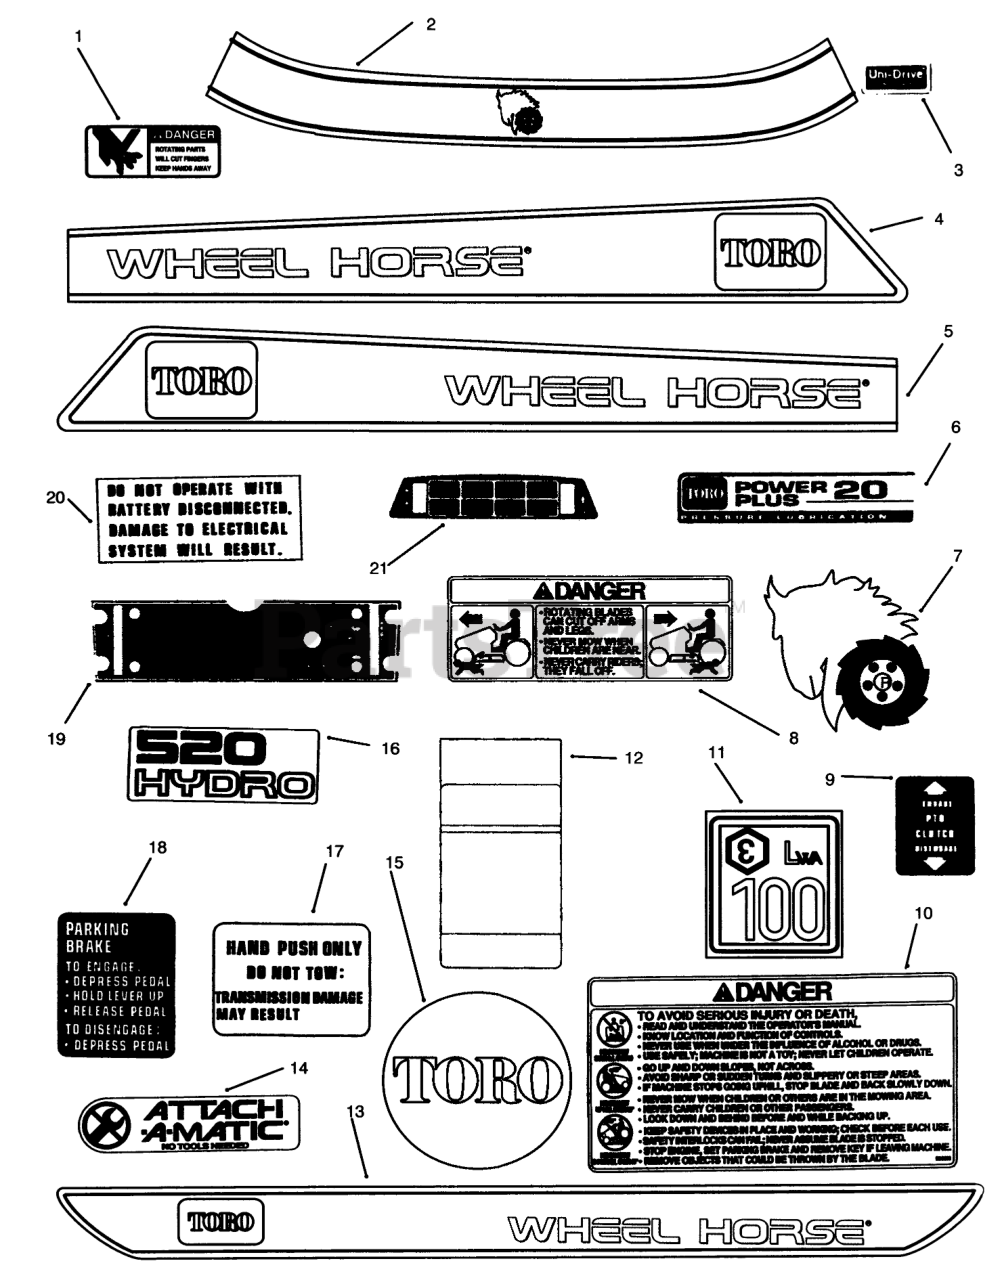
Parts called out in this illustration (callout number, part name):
1	DECAL - DANGER
2	DECAL-FRONT HOOD, TOP
3	Decal-Unidrive
4	DECAL - LH HOOD TOP
5	DECAL - RH HOOD TOP
6	DECAL-PWR PLUS 20 PL
7	PLATE - LOGO WHL HORSE
8	DECAL-DANGER
9	DECAL PTO CLUTCH
10	DECAL - DANGER
11	DECAL-EUROPE
12	Decal-Maintenance
13	DECAL - REAR FENDER
14	DECAL-ATTACH A-MATIC
15	NAME-PLATE TORO LOGO
16	Decal-520 Hydro
17	DECAL-DO NOT TOW
18	DECAL-PARKING BRAKE
19	DECAL-FRONT PANEL
20	DECAL ELECT SYSTEM
21	DECAL-IND LIGHTS
